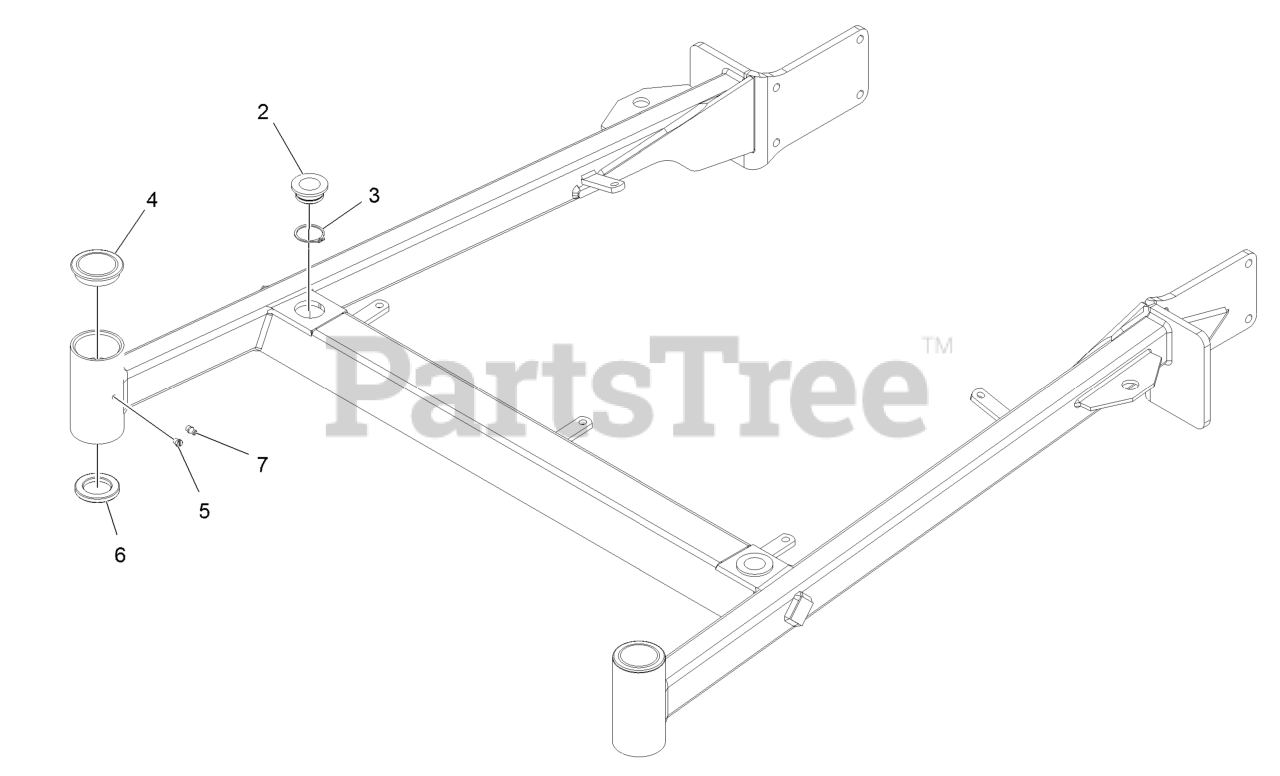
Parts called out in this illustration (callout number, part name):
2	Bushing-Deck
3	Ring-Retaining
4	Cap-Grease
6	Seal-Grease
7	Zerk-1/4-28 Str
